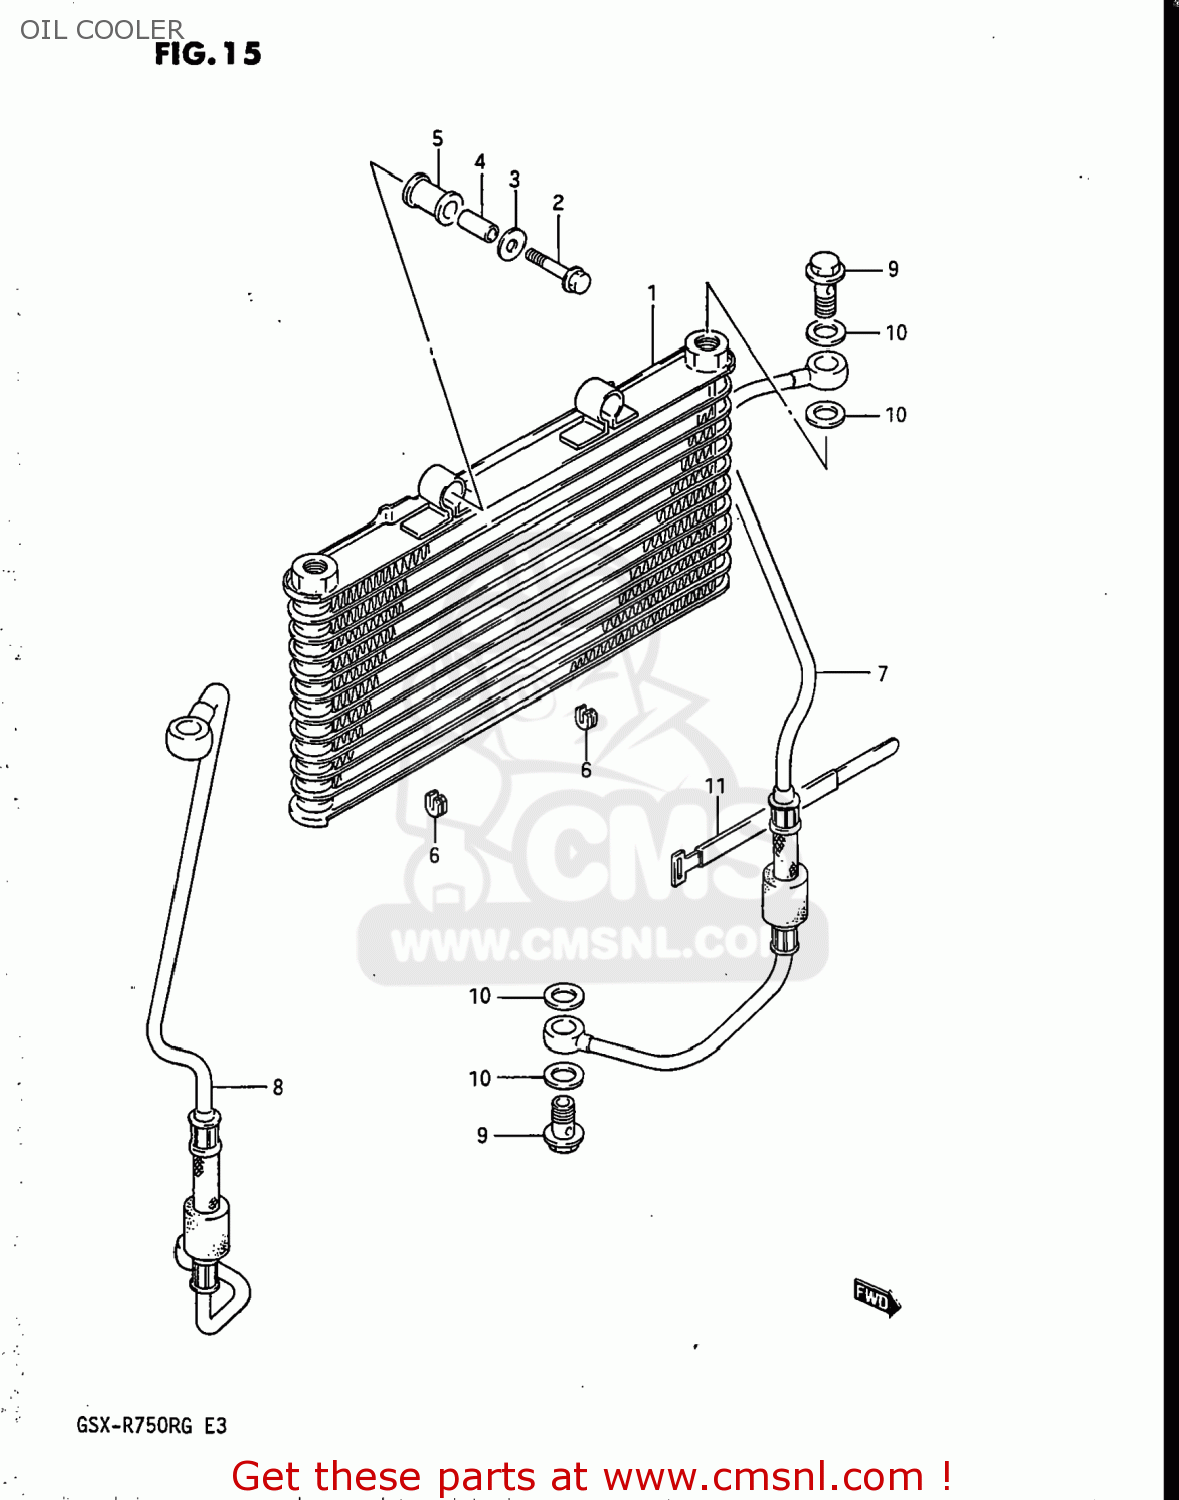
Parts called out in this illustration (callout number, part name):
1	COOLER ASSEMBLY,OIL
2	BOLT 8X40
3	WASHER(8.5X23X1.2)
4	SPACER (8.8X12X24.5)
5	CUSHION,OIL COOLER NO.1
6	CUSHION,OIL COOLER NO.2
7	HOSE,OIL
8	HOSE,OIL
9	BOLT,UNION
10	GASKET(16X22X2) (NAS)
11	CLAMP
